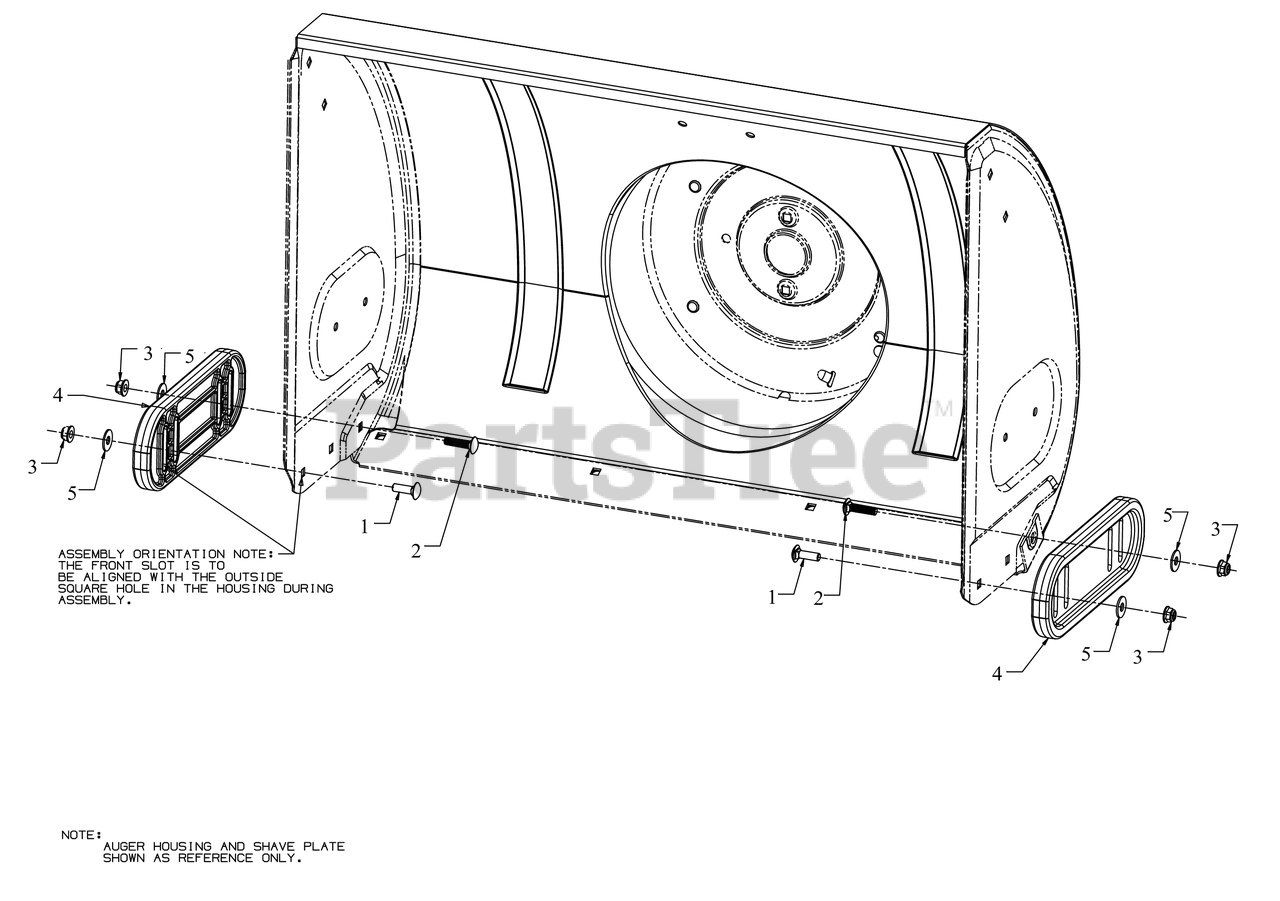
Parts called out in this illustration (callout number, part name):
1	CARRIAGE BOLT 5/16-18 x 1.00
2	CARRIAGE BOLT 5/16-18 X 1.25
3	FLANGE LOCK NUT 5/16-18
4	DELUXE SKID SHOE (POLY BLUE)
4	Cub Cadet SKID SHOE (COOL BLUE 731-11514)
5	FLAT WASHER
